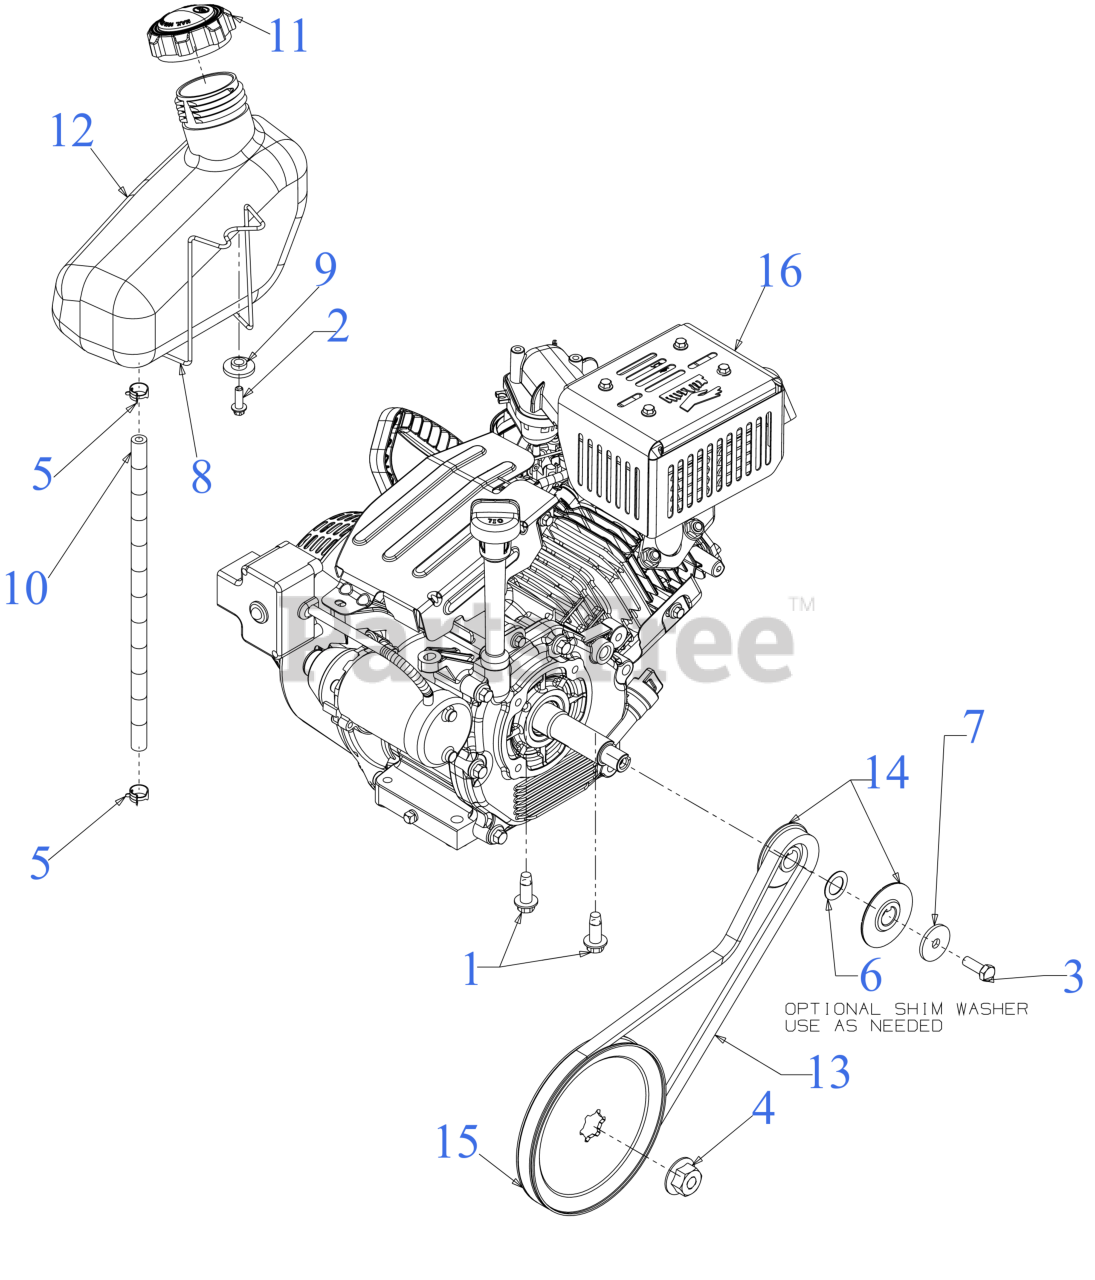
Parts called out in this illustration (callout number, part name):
1	SCREW 3/8-16 x 1
2	SCREW 1/4 x .750
3	SCREW 5/16-24 x .875 GR5
4	FLANGE NUT W/HUB
5	HOSE CLAMP 1/20
6	FLAT WASHER
7	WASHER-5/16 x 1.25X 1.27
8	FUEL TANK WIRE SUPPORT
9	SHOULDER SPACER
10	FUEL HOSE LOW PERMEATION 13"
11	FUEL CAP
12	FUEL TANK
13	V-BELT .500 x 35.00LG
13	Cub Cadet AUGER BELT
13	Genuine Factory Parts AUGER BELT
14	HALF PULLEY
15	AUGER PULLEY
16	COMPLETE ENGINE 123cc
